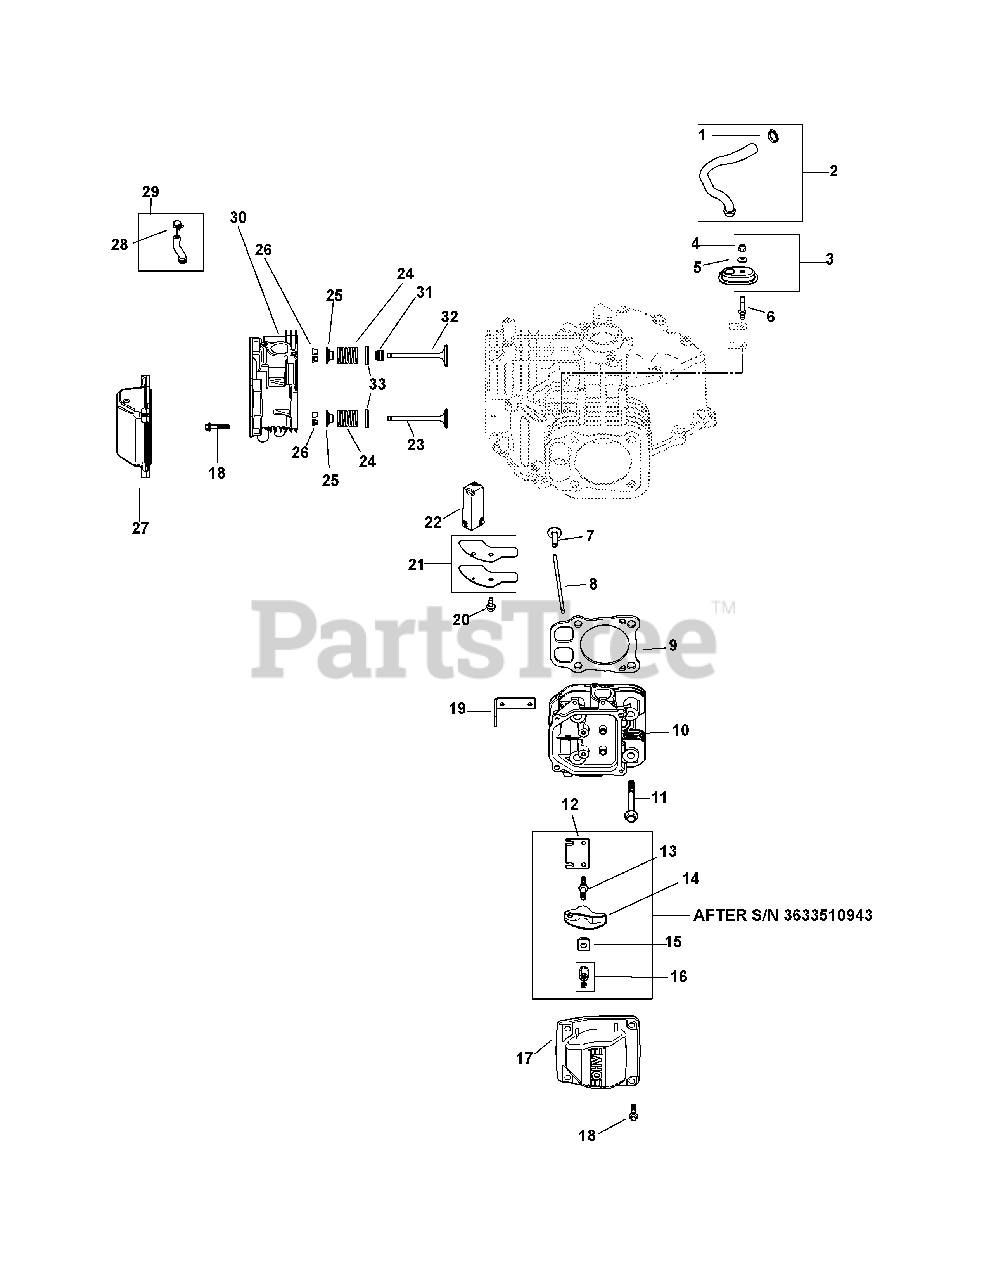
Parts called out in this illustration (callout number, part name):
1	Clamp, Hose 1/2''
2	Kit, Breather Hose
3	Kit, Breather Housing
4	Nut, Lock M5X.8
5	Washer, Sealing
6	Stud, Breather Cover
8	Rod, Push
9	Kit, Cylinder Head Gasket
10	Kit, #2 Cylinder Head Assembly
11	Screw, Flg M10X1.5X90
13	Stud, Rocker
15	Pivot, Rocker Arm
16	Hex Nut Assembly
17	Cover, Rocker Stamped Steel
18	Screw, Pan Head
20	Screw, Flg Thd Frm M6X1.0X16
21	Cover, Breather
22	Filter, Breather
23	Valve, Exhaust (Std)
24	Spring, Valve
25	Cap, Valve Spring
26	Kit, Retainer
27	Cover, Rocker Stamped Steel
29	Kit, Fuel Pump Hose
30	Kit, #1 Cylinder Head Assembly
31	Seal, Valve Stem
32	Valve, Intake (Std)
33	Retainer, Spring
